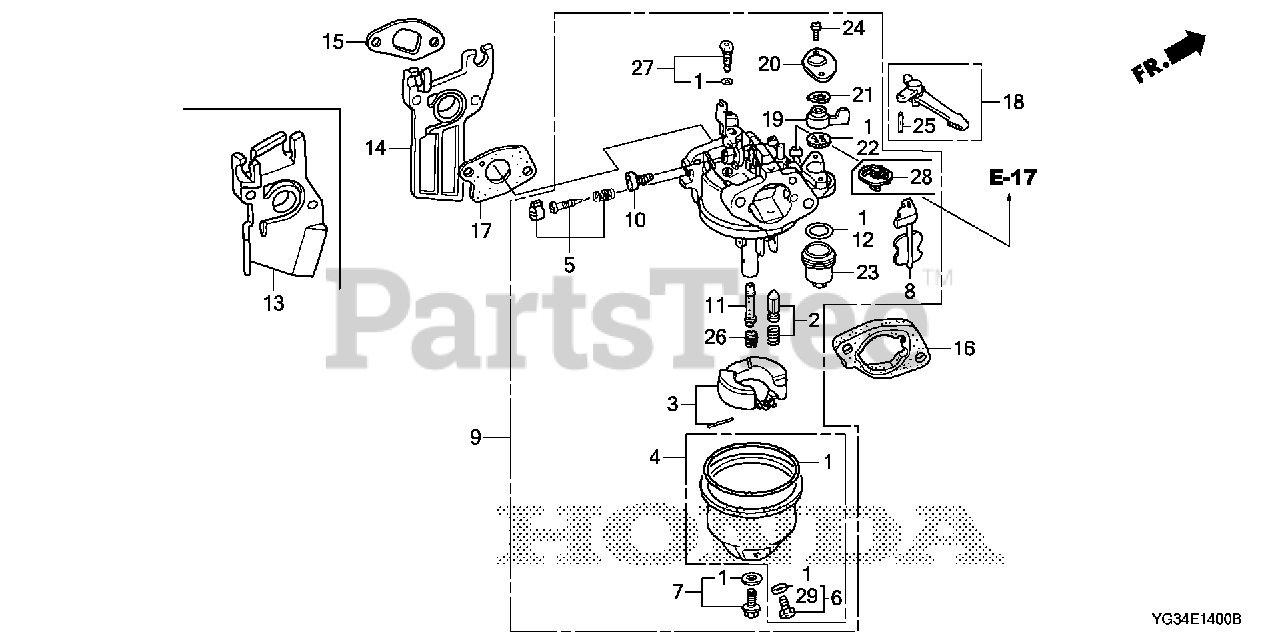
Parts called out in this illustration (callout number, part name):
1	GASKET SET
2	VALVE SET, FLOAT (CARBURETOR NO.) (SEAT NOT INCLUDED)
3	FLOAT SET
4	CHAMBER SET, FLOAT
5	SCREW SET (Honda Code 4219879). (CARBURETOR NO.)
6	SCREW SET, DRAIN
7	SCREW SET (CARBURETOR NO.)
8	CHOKE SET (CARBURETOR NO.)
9	CARBURETOR ASSY. (BE54D A)
10	SCREW, THROTTLE STOP
11	NOZZLE, MAIN
12	GASKET, FUEL STRAINER CUP
14	INSULATOR, CARBURETOR
15	GASKET, INSULATOR
16	SPACER, CARBURETOR
17	GASKET, CARBURETOR
18	LEVER, CHOKE (STD)
19	LEVER, VALVE
20	PLATE, LEVER SETTING (CARBURETOR NO.)
21	SPRING, PETCOCK LEVER (CARBURETOR NO.)
22	GASKET, VALVE
23	CUP, FUEL STRAINER
24	SCREW, PAN (3X6)
25	PIN, SPRING (2X12)
26	JET, MAIN (#62)
26	JET, MAIN (#68)
26	JET, MAIN (#65)
27	JET SET, PILOT (#35)
28	FILTER, CUP (CARBURETOR NO.)
